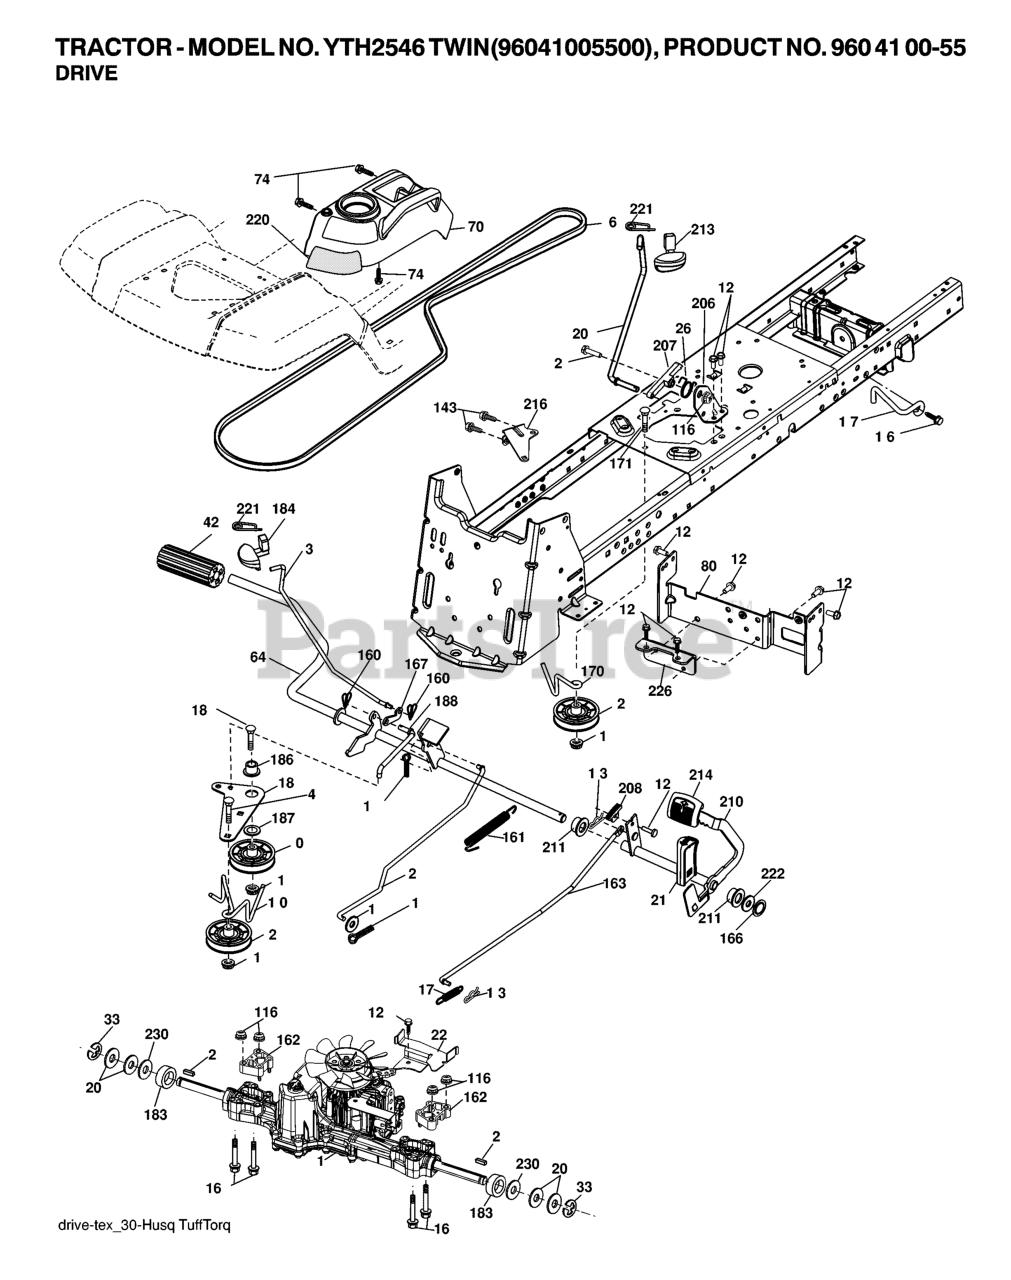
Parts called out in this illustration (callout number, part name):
2	SQUARE KEY
15	WASHER
17	SPRING.BRAKE.K46
26	SPRING.RETURN.CRUISE
29	ROD.BRAKE.K46
35	ROD.BRAKE.PARKING.GT.H
42	PEDAL COVER T
50	IDLER.FLAT.910.OFFSET
51	NUT LOCK FLG 3/8-16 UNC
52	IDLER.V-GROOVE.910.OFFSET
56	V-BELT.MOWER.92.40.42/K46
64	SHAFT.ASM.PEDAL.BRK.CNTR
70	RP CONSOLE.ASM.PCH.W/TB
74	SCREW.HI-LO.CONSOLE
80	STRAP.TORQUE.HG3000/K46
92	BOLT
116	NUT LOCK HEX FLANGE 5/16-18
125	SCREW
143	Screw 5/16-18 x 1/2 Hex, Self Tapping 5/16-18 x 1/2
153	RETAINER M
159	COTTER PIN
160	RETAINER CLIP
161	SPRING.RETURN.CLUTCH.2006
162	SPACER.TRANSAXLE.18&22
163	ROD.CONTROL.PEDAL.K46
166	NUT.PUSH.625.2006
167	LATCH.BRAKE.SPRING
169	BOLT.HEX.FLNG.5/16-18X3.75
170	KEEPER.V-IDLER.CENTER.
183	SPACER AXLE
184	HANDLE.PARKG.BRK.HUSQ X667
186	SPACER.RETAINER
187	WASHER 12/32X2X10GA
188	RP.LINK.CLUTCH.GROUND.DRIVE
189	BELLCRANK.GROUND.DRIVE.TEX.
190	KEEPER.BELLCRANK.DRIVE
196	SCREW 3/8-16X1
197	LINK.CLUTCH.ANIT-ROTAT
206	BRKT.MOUNT.LATCH.CRUIS
207	LATCH.CONTROL.CRUISE
208	GEAR.SECTOR.CONTROL.CR
209	ROD.CONTROL.CRUISE.GT.
210	ROCKER.ASM.PEDAL.CONTR
211	BEARING.NYLON
213	KNOB.CONTROL.CRUSIE.HU
214	PEDAL.FORWARD.TEX.GT.4
215	PEDAL.REVERSE.TEX.GT.4
216	BRACKET.PULLEY.IDLER.W/TEX
220	REFLECTOR.RH.TEX GT
221	RETAINER.SPRING.CLIP.H
222	WASHER 21/32 X 1-1/4 X 10 GA.
225	KEEPER.BELT.TRANSAXLE.K46
226	BRKT.MOUNT.TORQUE.K46.
230	WASHER.HARDENED
